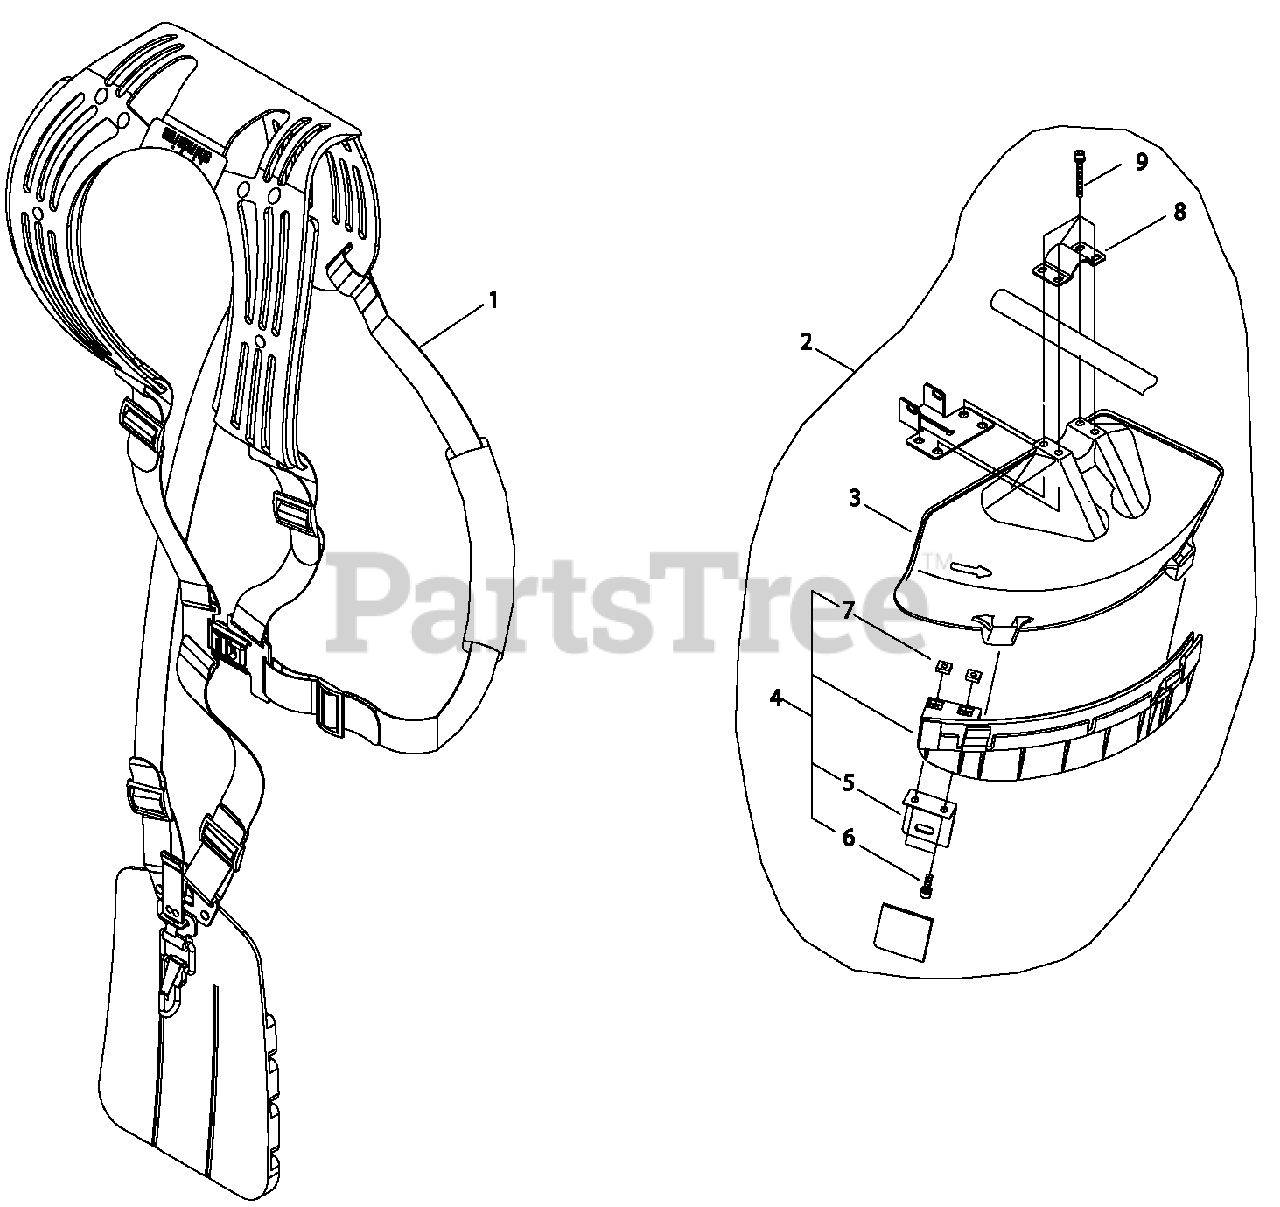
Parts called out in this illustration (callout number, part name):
1	HARNESS ASSY
2	DEBRIS SHIELD KIT
3	SHIELD, DEBRIS PLASTIC
4	DEBRIS SHIELD EXTENSION ASSY
5	CUTTER
6	BOLT M5×16
7	NUT M5
8	CLAMP, UPPER
9	BOLT M5×45
